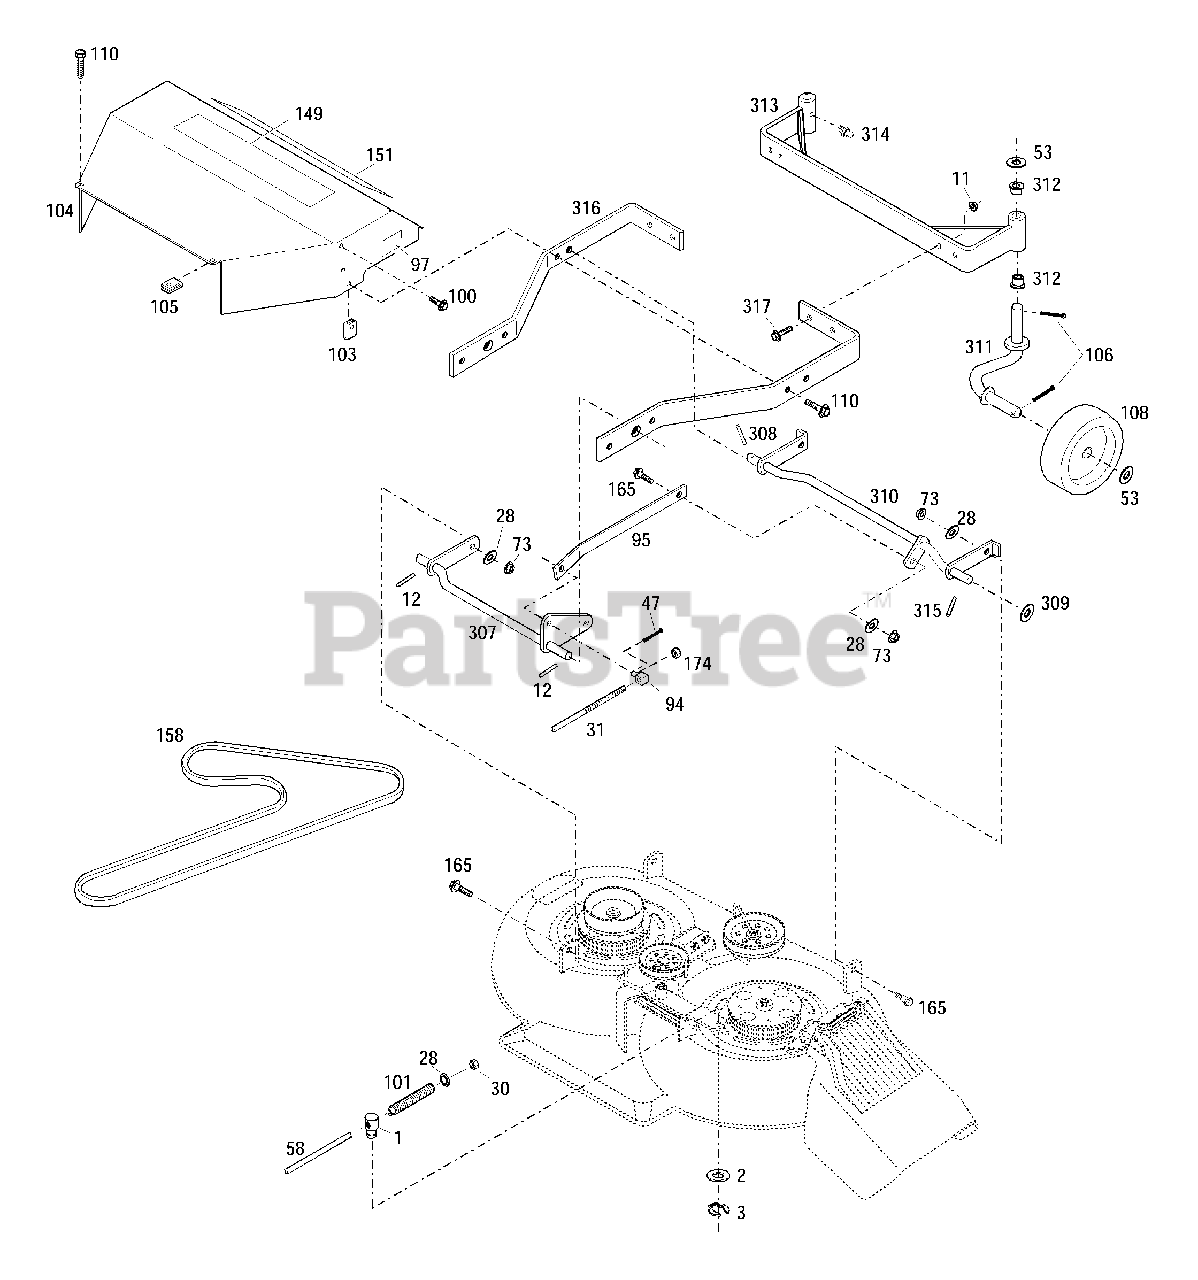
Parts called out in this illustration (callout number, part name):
3	Clip Ring
11	Flange Locknut, 3/8-16
28	Flat Washer, 3/8
30	Locknut, 3/8-16
31	Lift Crank
47	Cotter Pin
53	Special Washer
58	Lower Blade Rod
73	Flange Locknut, 3/8-16
94	Pivot Block
95	Leveler Bar
97	Cutting Height Decal
100	Tap Screw, #8 x 3/8
101	Compression Spring
103	Speed Nut, 5/16-18
104	Belt Guard
105	Speed Nut, 5/16-18
106	Cotter Pin
108	Gage Wheel
110	Flange Lock Screw, 5/16 x 3/4
149	Logo Decal
151	33" Combination Deck Decal
165	Shoulder Bolt
174	Toplock Nut
307	Rear Lift Assembly
308	Roll Pin, 1/4 x 1
309	Flat Washer, 5/8
310	Front Lift Assembly
311	Spindle Assembly
312	Flange Bearing
313	Gage Support
314	Grease Fitting
315	Drive Pin, 1/4 x 3
316	Mower Support
317	Whizlock Screw, 3/8-16 x 1
402	Black Spray Paint Can, 13 Oz.
